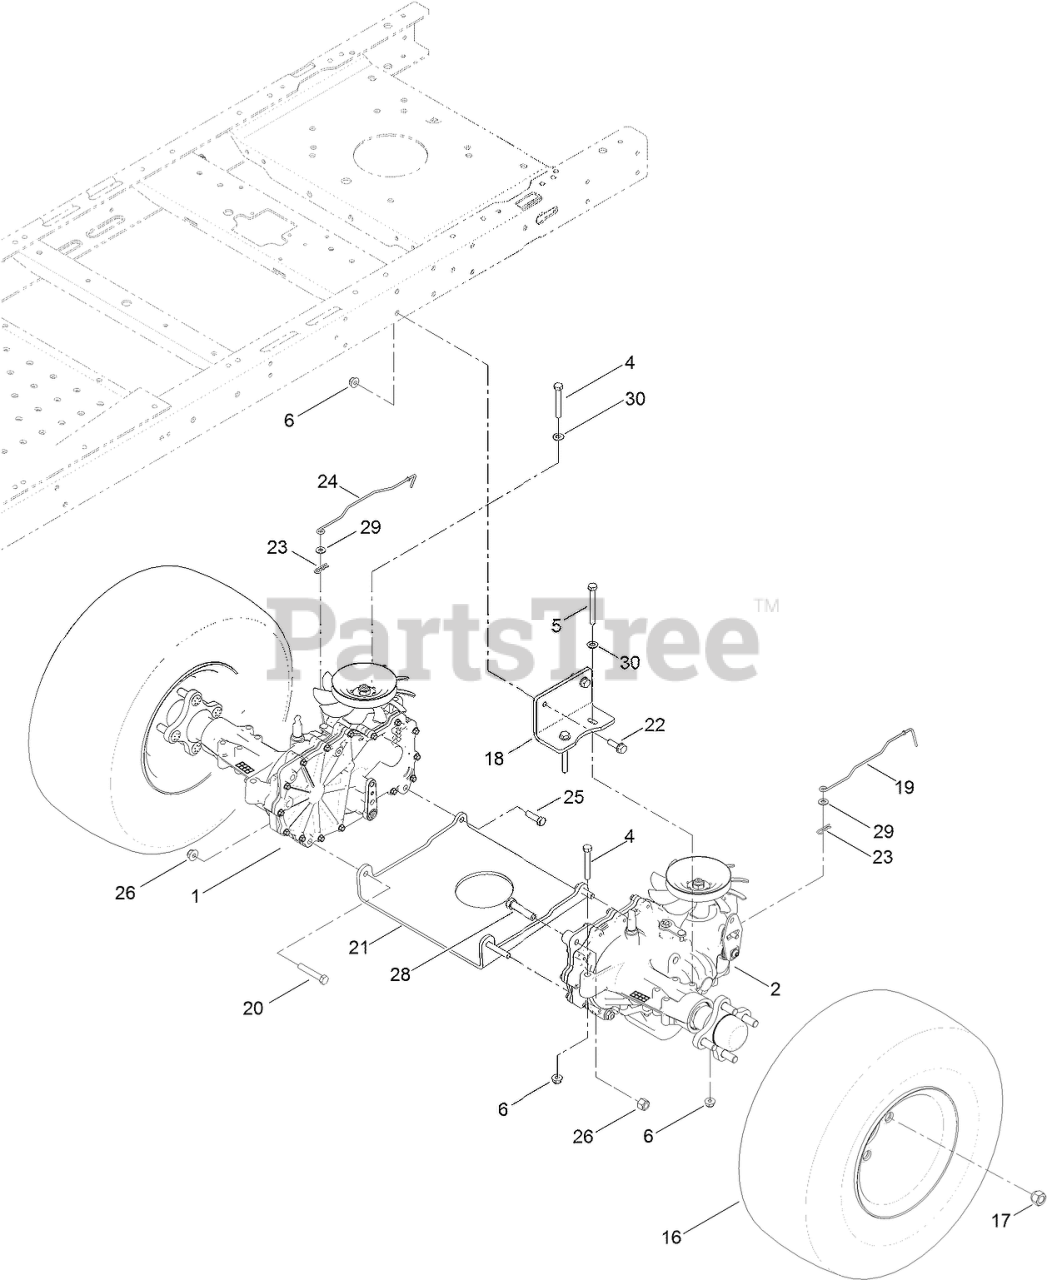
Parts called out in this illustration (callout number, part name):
1	RH HYDRO TRANSMISSION ASM
2	LH HYDRO TRANSMISSION ASM
4	SCREW-HH
5	SCREW-HH
6	NUT-HF, NI
16	2 PLY TIRE AND WHEEL ASM
17	NUT-LUG
18	MOUNT-HYDRO
19	ROD-BYPASS, LH
20	SCREW-HH
21	PLATE-CROSS, HYDRO
22	SCREW-HHF
23	PIN-COTTER
24	ROD-BYPASS, RH
25	SCREW-HH
26	NUT-HF, NI
28	SCREW-HH
29	WASHER
30	WASHER-PLAIN
